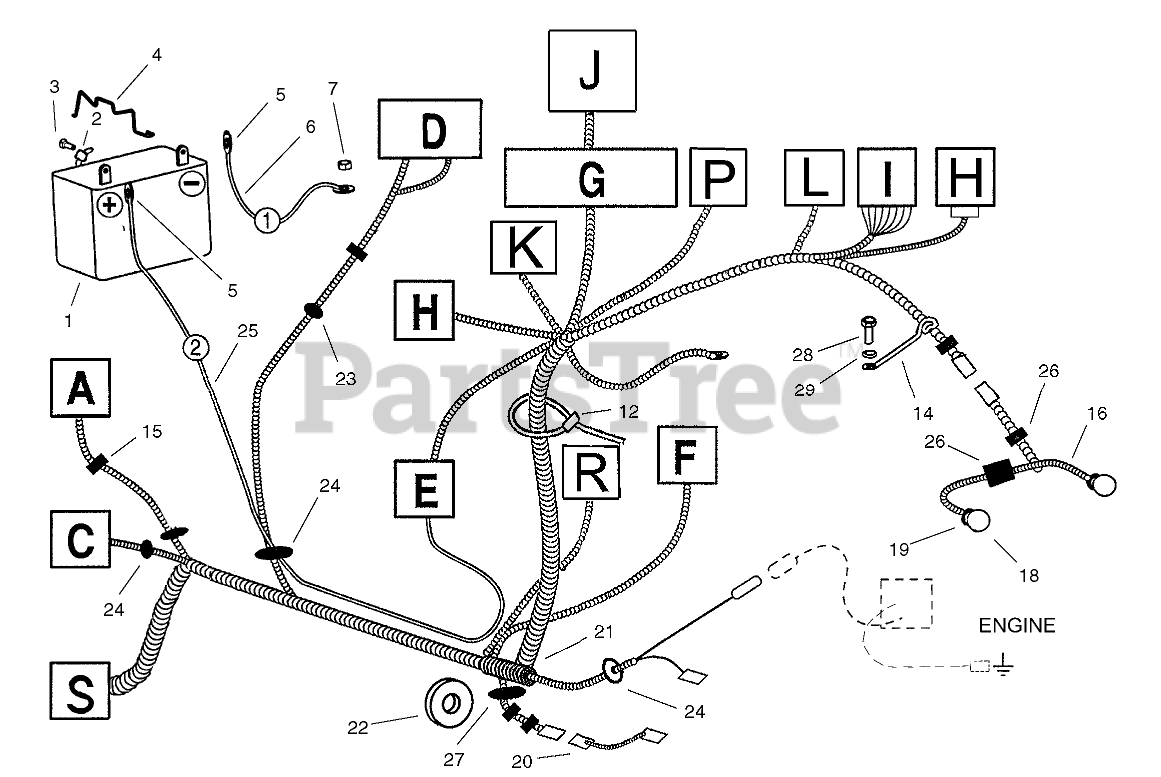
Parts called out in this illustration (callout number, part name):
1	BATTERY-12V
2	NUT-HHF
3	SCREW-HH
4	CLAMP-BATTERY
5	BOOT-RUBBER
6	CABLE-BATTERY, Negative
7	NUT-LOCK, NI
12	TIE-CABLE
14	HOLDER-HARNESS, WIRING
15	CLIP-SNAP
16	HARNESS-WIRE, LIGHTS
18	BULB-LIGHT
19	SOCKET-LIGHT
20	HARNESS-CLUTCH
21	HARNESS-WIRING
23	BUSHING
24	BUSHING
25	CABLE-BATTERY POSITIVE
26	CLIP-NYLON
27	BUSHING
28	SCREW-HH
29	WASHER-PLAIN
